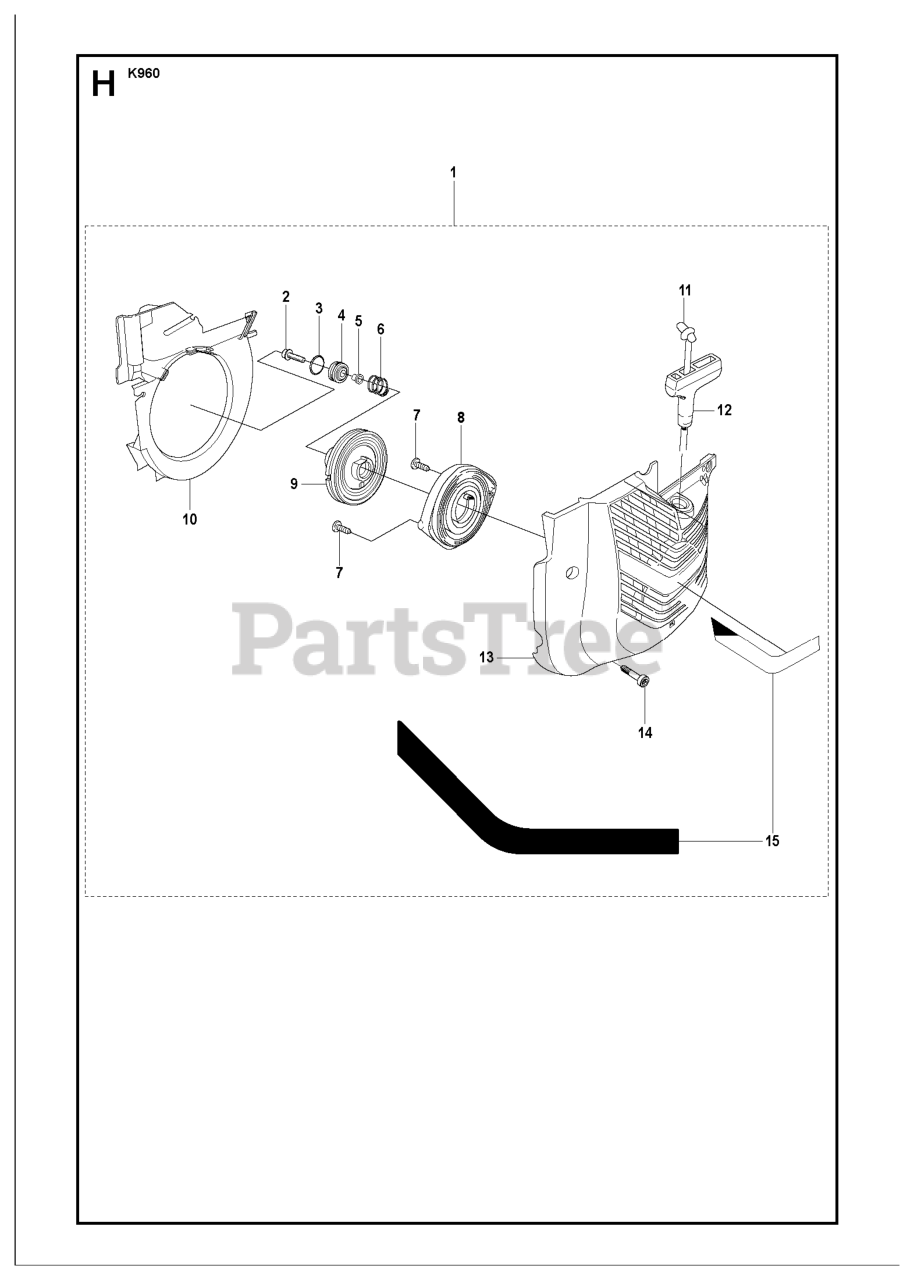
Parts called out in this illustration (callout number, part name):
1	STARTER
2	SCREW
4	RP WASHER
8	RETURN SPRING
9	STARTER PULLEY
10	RP COOLING AIR CONDUCTOR
11	STARTER ROPE 50 M
11	STARTER ROPE
12	STARTER HANDLE
13	STARTER COVER
15	LABEL X-TORQ STARTER
